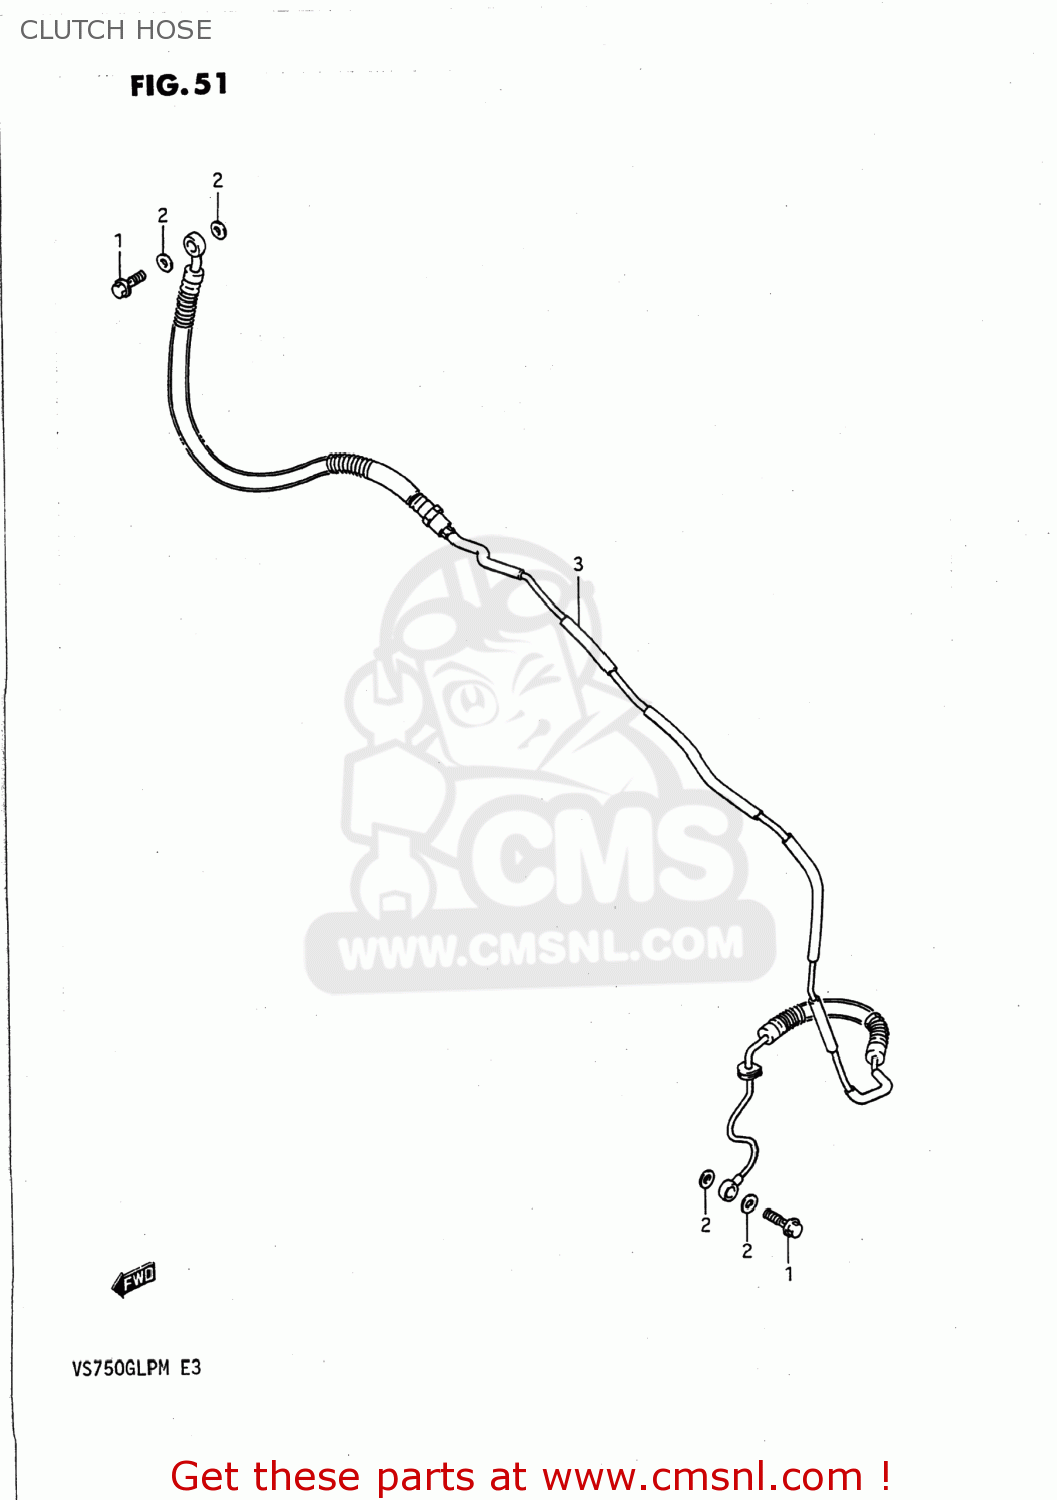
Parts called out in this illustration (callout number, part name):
1	BOLT UNION
2	WASHER(10X15X1.5)
3	HOSE ASSY,CLUTCH
